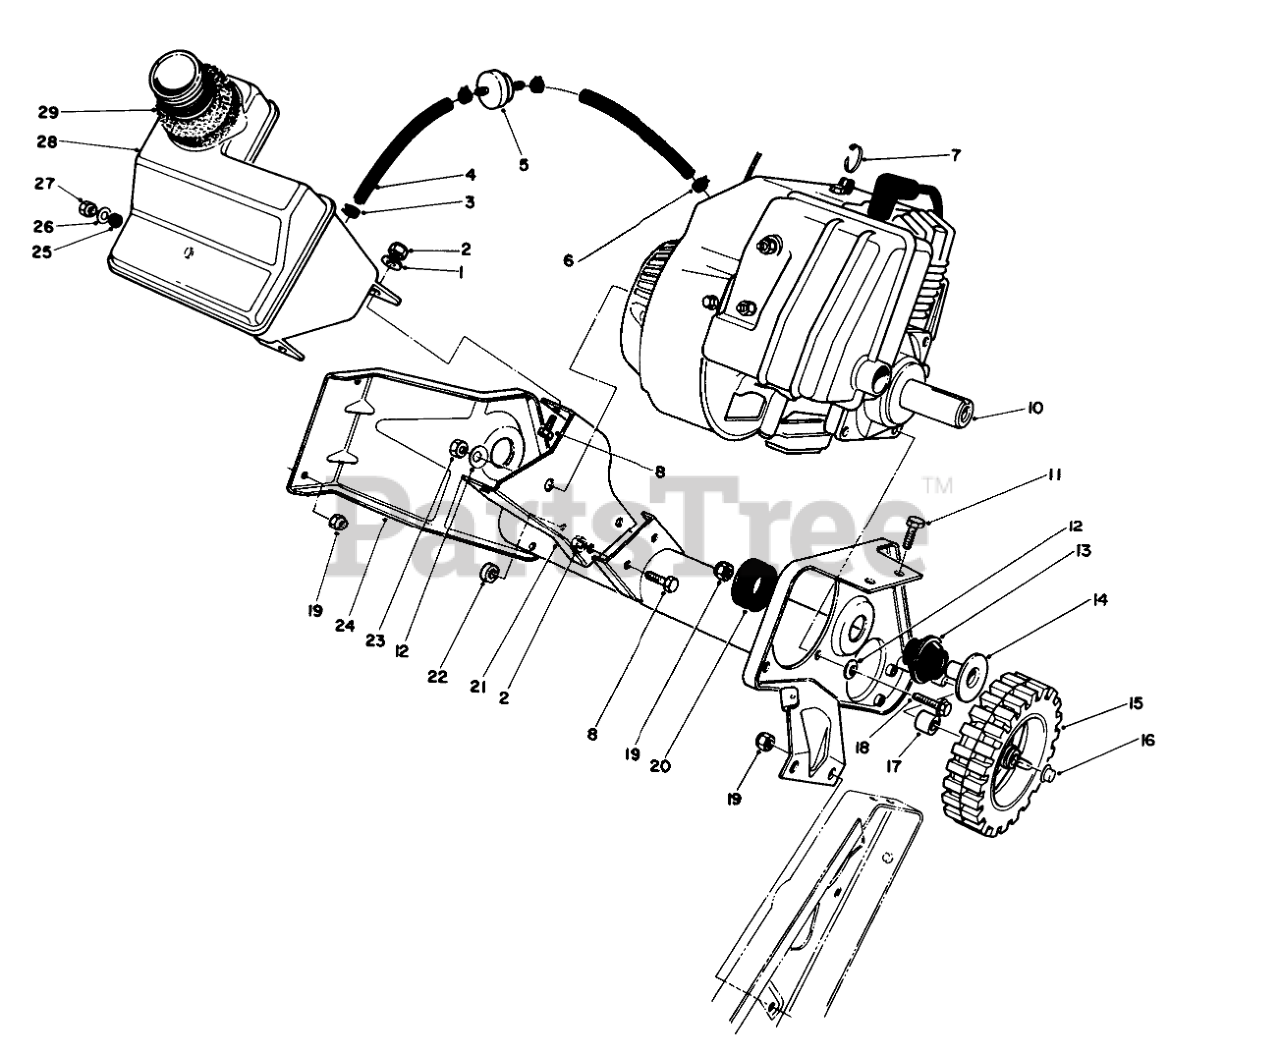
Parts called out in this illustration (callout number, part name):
1	WASHER-FLAT
2	NUT-LOCK, NI
3	Clamp
4	GAS LINE
5	FILTER-FUEL
6	CLAMP-HOSE
7	TIE-CABLE
8	SCREW-HH
10	Engine ASM
11	SCREW-HH
12	WASHER-BELLEVILLE
13	MOUNT-REBOUND
14	SPACER TUBE
15	WHEEL
16	NUT-PUSH
17	SPACER-WHEEL
19	NUT-LOCK, NI
20	LOAD MOUNT
21	Support-Recoil
22	SPACER-WHEEL
23	NUT (F/W & PPP)
24	Wa-Frame
25	GROMMET-RUBBER
26	WASHER-PLAIN
27	NUT-LOCK, CONE
28	Tank-Fuel (Incl. Ref. #25)
29	SEAL-FOAM
